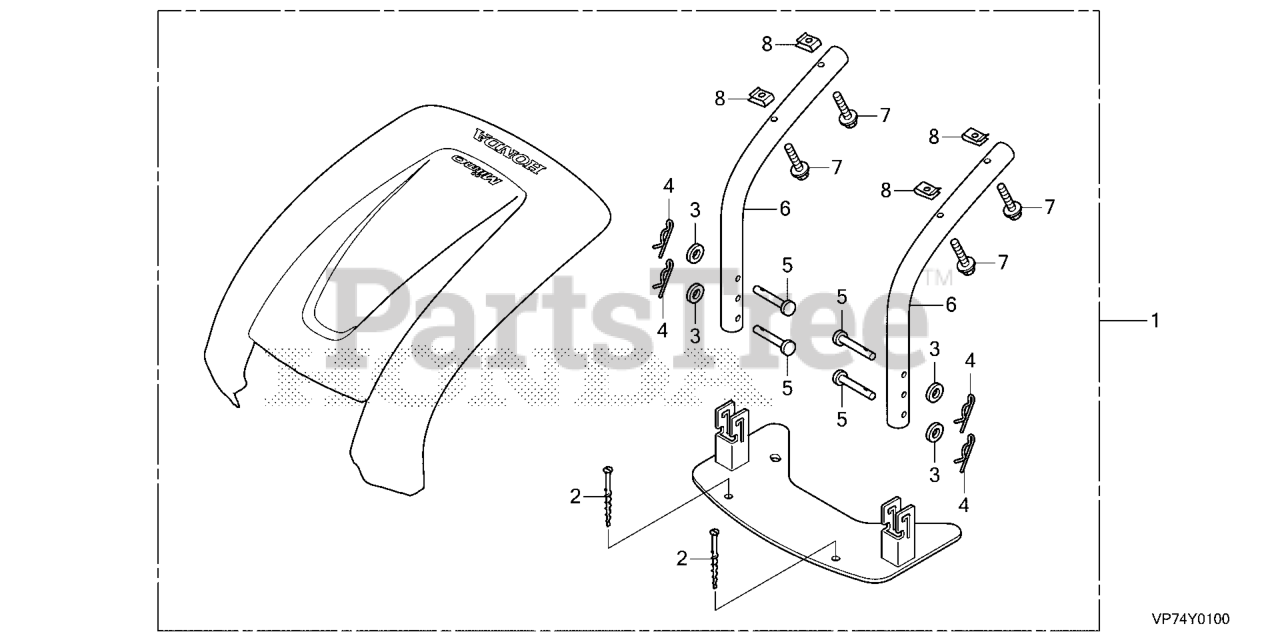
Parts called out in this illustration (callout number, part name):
1	ROOF KIT, STATION
2	PEG, STATION
3	WASHER, PLAIN (6MM)
4	PIN, LOCK (6MM)
5	PIN, PITCH STEP
6	PIPE, HINGE
7	BOLT, FLANGE (6X35)
8	NUT, CLIP (6MM)
